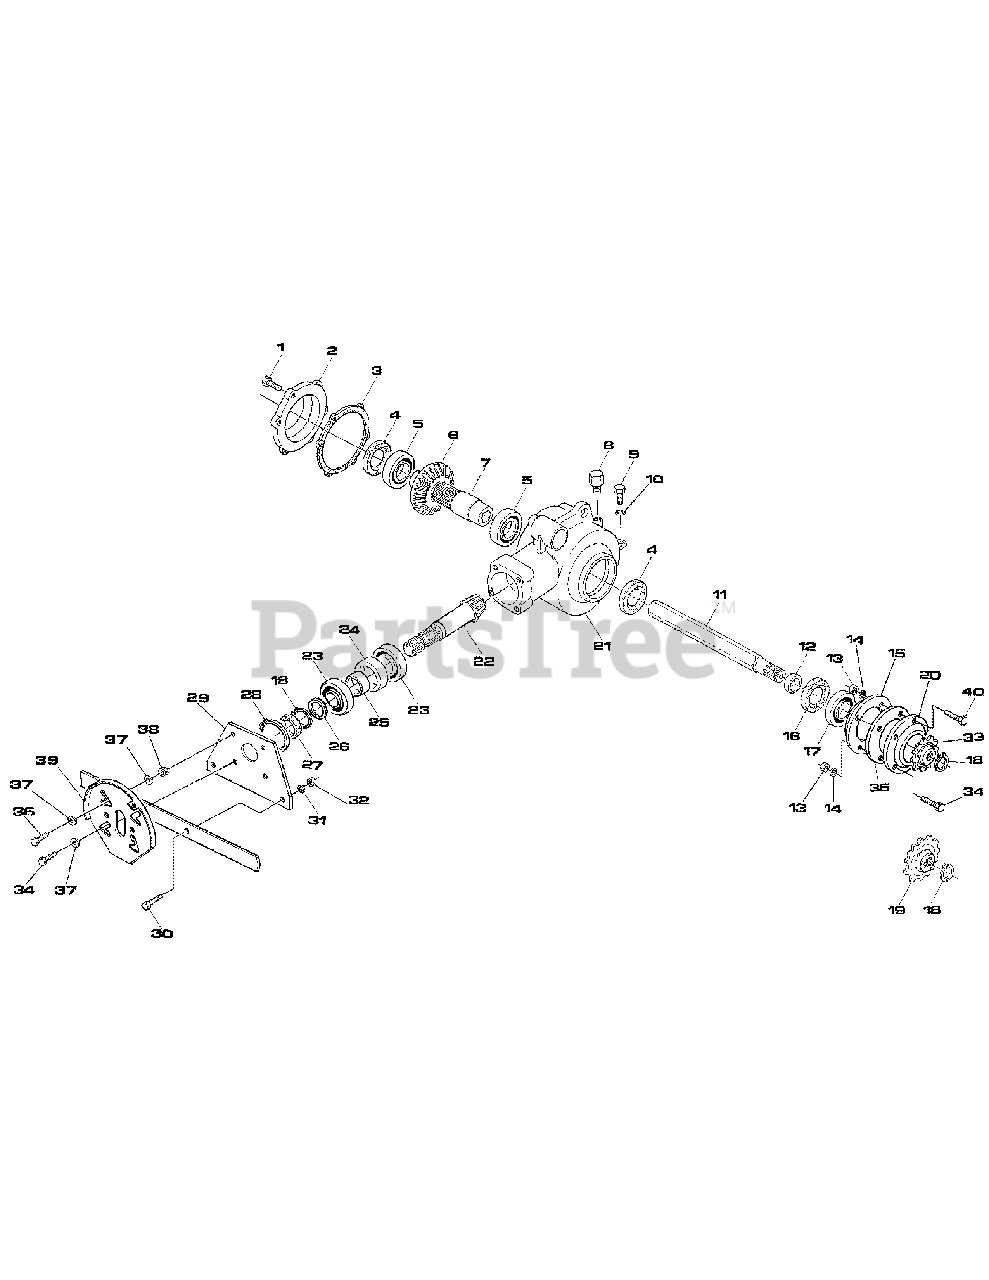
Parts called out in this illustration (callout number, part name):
1	Bolt TE M10x20
2	Gear cover
3	Gasket
4	Oil seal 50.68.10
5	Bearing 6010
6	Ring gear
7	Shaft coupling
8	Breather cap
9	Bolt TE M12x40
10	Flat washer Ø12
11	Hexagonal shaft RT42
11	Hexagonal shaft RT66
12	Spacer
13	Nut M10
14	Spring washer Ø10
15	Cover
16	Oil seal 45.60.10
17	Bearing 6307
18	Outer snap ring Ø35
19	Sprocket Z14
20	Left outer cover
21	Gearbox
22	Pinion gear
23	Bearing 6207
24	Outer spacer
25	Inner spacer
26	Spacer washer
27	Oil seal 35.72.10
28	Inner snap ring Ø72
29	Gearbox front cover
30	Bolt TE M12x30
31	Spring washer Ø12
32	Nut M12
33	Sprocket Z11
34	Bolt TE M10x30
35	Disk with holes
36	Bolt TE M10x35
37	Flat washer Ø10
38	Nut M12
39	Protection support
40	Bolt TE M10x45
